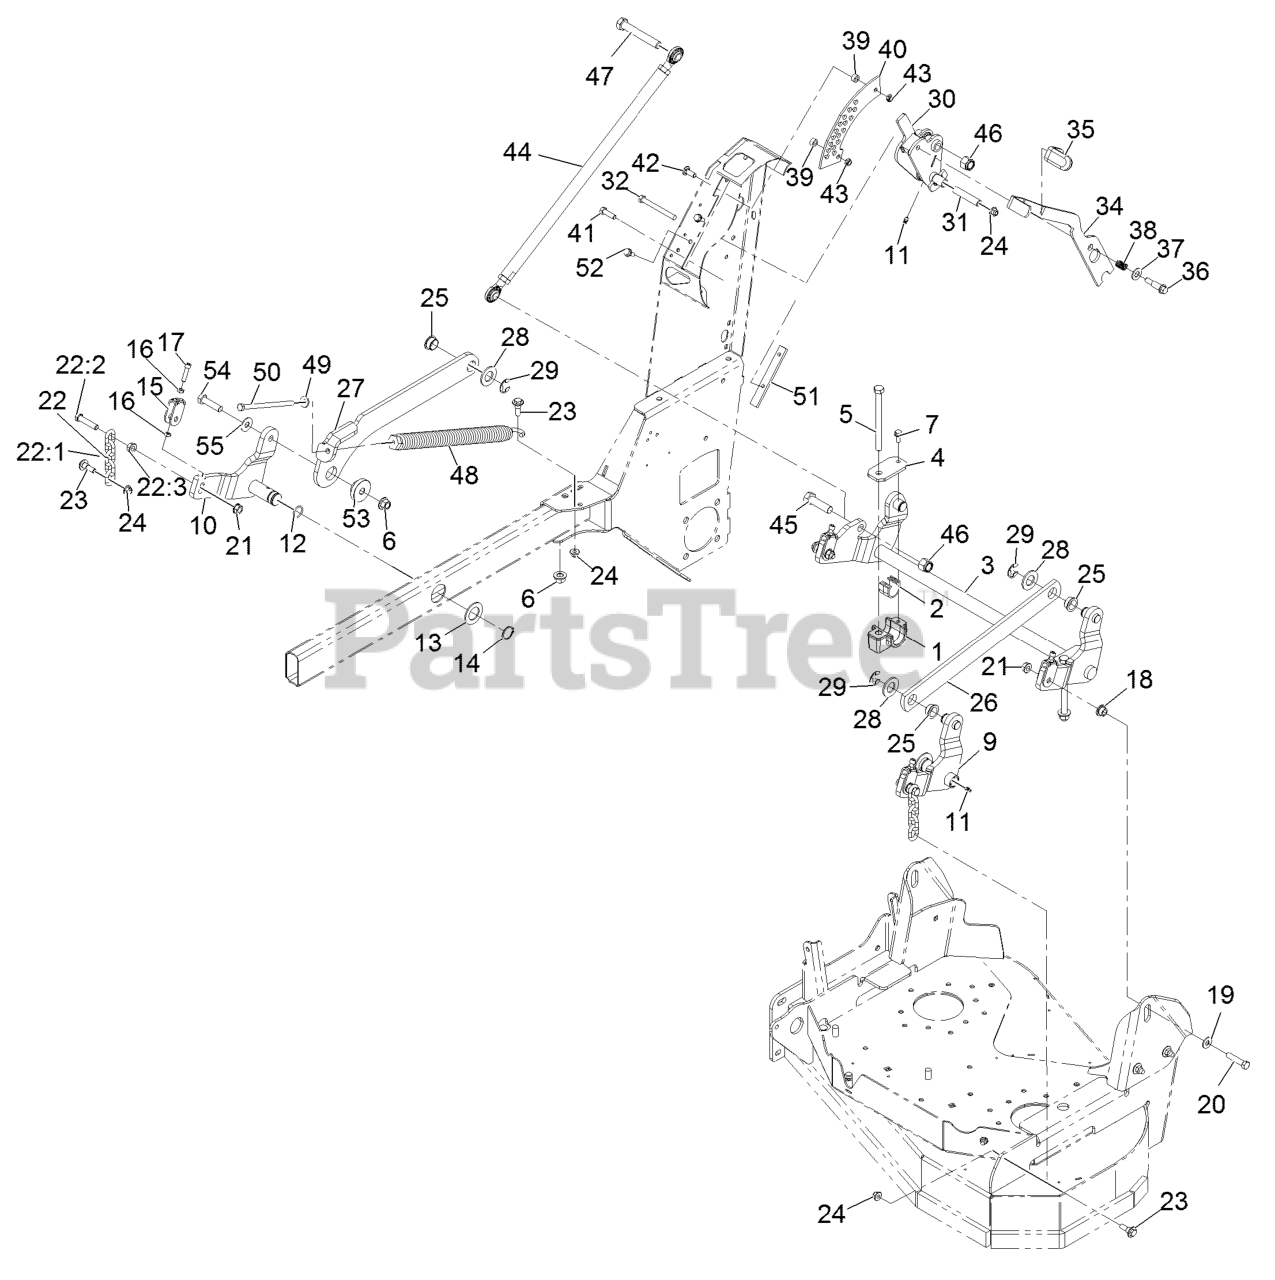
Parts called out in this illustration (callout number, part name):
1	SUPPORT-BEARING
2	BEARING-CROSS SHAFT, FRON
3	REAR CROSSSHAFT ASM
4	COVER-BEARING SUPPORT
5	SCREW-HH
6	Nut-Lock 1/2-13
7	SCREW-HHF
9	DECKLIFT ARM ASM-LH
10	DECKLIFT ARM ASM-RH
11	FITTING-GREASE
12	O RING
14	RING-RETAINING
15	YOKE-ADJUST, DECK
16	NUT-JAM
17	SCREW-HSH
18	BUSHING-FLANGED
19	WASHER-FLAT
20	SCREW-HH
22	DECK LIFT CHAIN ASM
22:1	CHAIN-LIFT, DECK
22:2	SCREW-HH
23	SCREW-SHOULDER, HHF
24	NUT-HF, NI
25	BEARING-FLANGE
26	LINK-DECKLIFT, LH
27	LINK-DECKLIFT, RH
28	WASHER-FLAT
29	RING-RETAINING, EXT
30	ASM-HOC HANDLE
31	BEARING-HOC PIVOT
32	SCREW-HH
34	LEVER-HOC
35	GRIP-LEVER
36	SCREW-SHOULDER
37	WASHER-FLAT
39	SPACER
40	BRACKET-HOC
41	SCREW-HH
42	SCREW-CARR
44	HOC LINK ASM
45	SCREW-HH
46	NUT-LOCK, NI
47	SCREW-HH
48	SPRING-EXTENSION
49	WASHER-BELLEVILLE
50	BOLT-TAP, HH
51	SKID-HANDLE, LIFT
52	SCREW-THD ROLL, HWH
53	BUSHING-FLANGED
54	SCREW-HH
55	WASHER-FLAT
